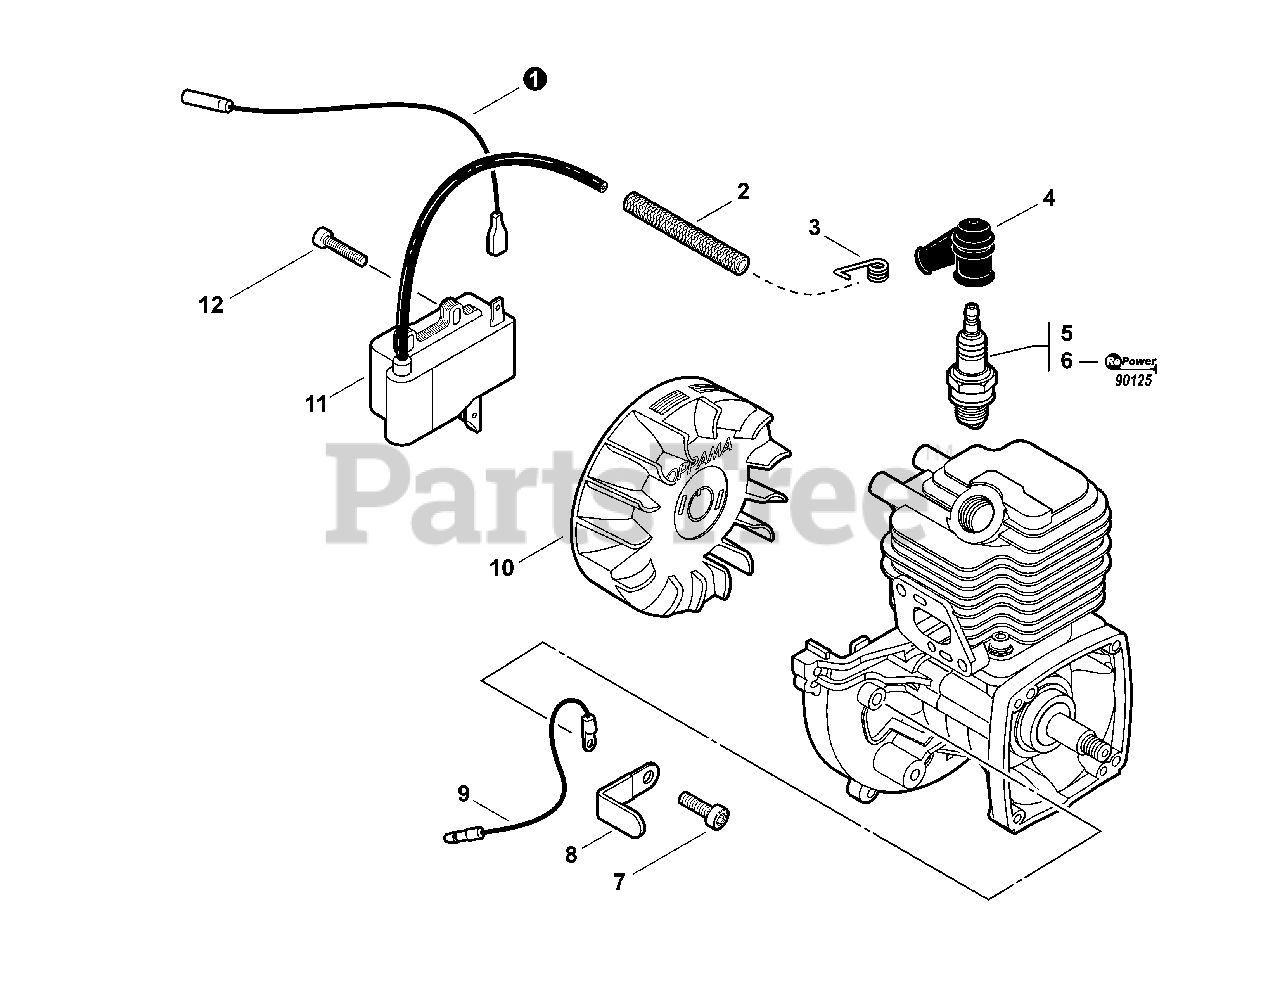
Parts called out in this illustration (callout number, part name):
1	LEAD - IGNITION L= 210
2	TUBE, INSULATOR Ø8 L= 65
3	TERMINAL, SPARK PLUG
4	CAP, SPARK PLUG
5	SPARK PLUG - BPM8Y
6	SPARK PLUG - BPMR8Y
7	BOLT, TORX 5×10
9	LEAD - GROUND L= 115
10	FLYWHEEL
11	COIL, IGNITION
12	BOLT, TORX 4×20
